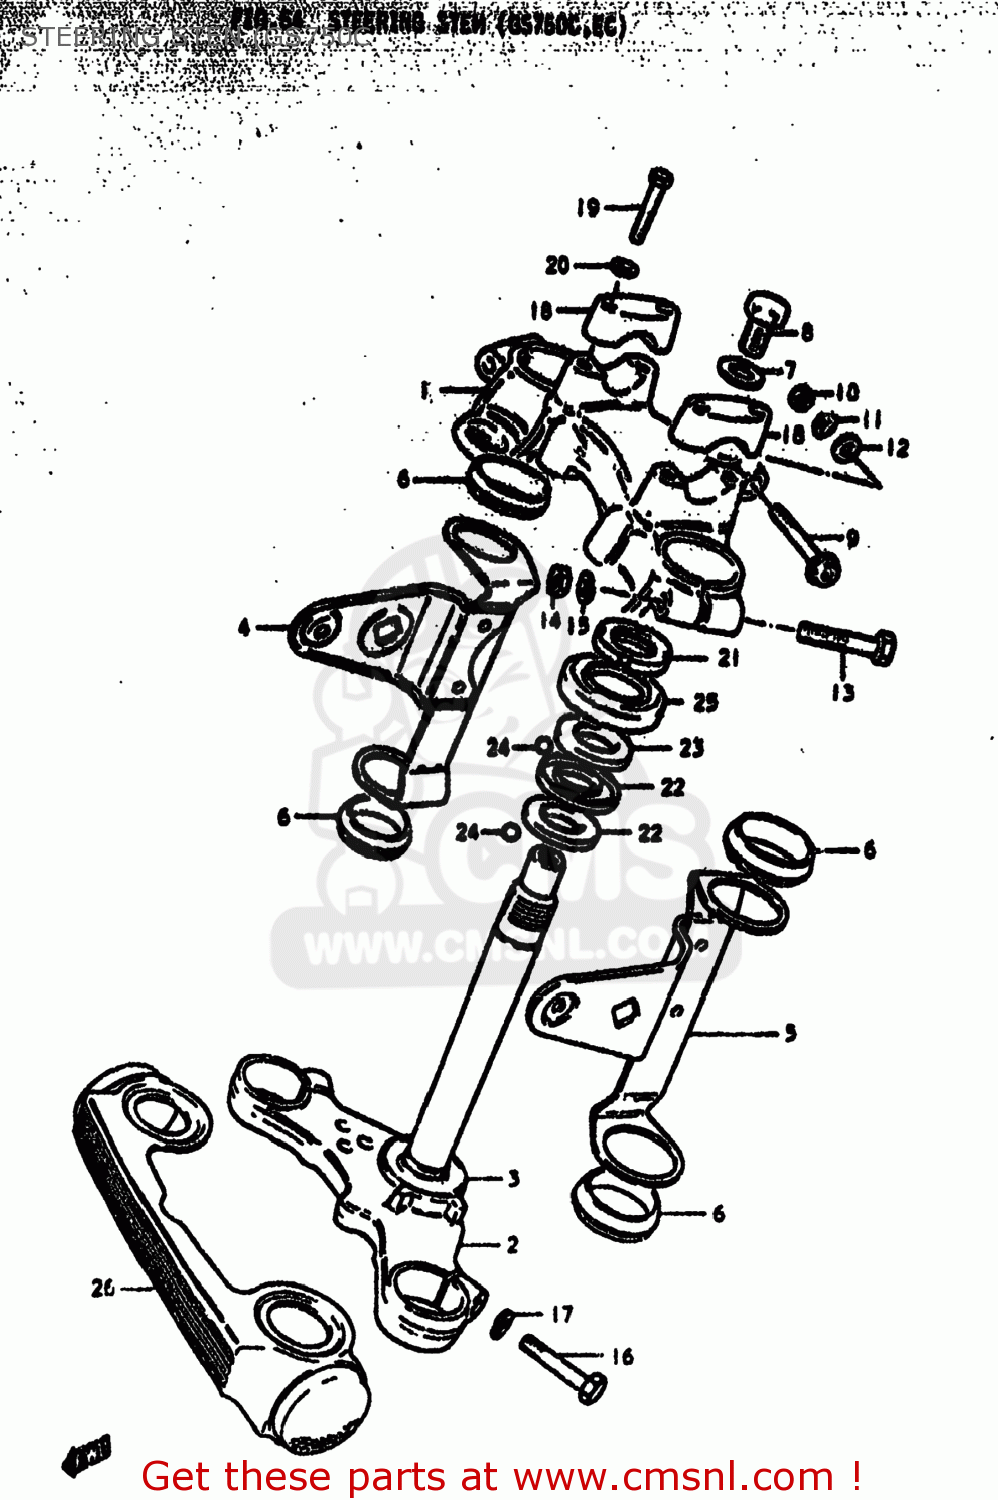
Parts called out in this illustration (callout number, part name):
1	HEAD,STEERING STEM
2	STEM,STEERING
3	RACE,STEERING OUTER LWR
4	BRACKET,HEADLAMP,RIGHT
5	BRACKET,HEADLAMP,LEFT
6	CUSHION,HEADLAMP BRACKET
7	WASHER
8	BOLT(12X20)
9	BOLT
10	NUT
11	LOCK WASHER
12	WASHER
13	BOLT 10X55
14	NUT
15	LOCK WASHER
16	BOLT 10X40
17	LOCK WASHER
18	HOLDER,HANDLE UPR
19	BOLT
20	LOCK WASHER
21	NUT,STEERING STEM(25X44X10)
22	LACE,STEERING INNER LWR
23	LACE,STEERING OUTER UPR
24	BALL
25	DUST SEAL,STEERING UPR
26	COVER,FR FORK
